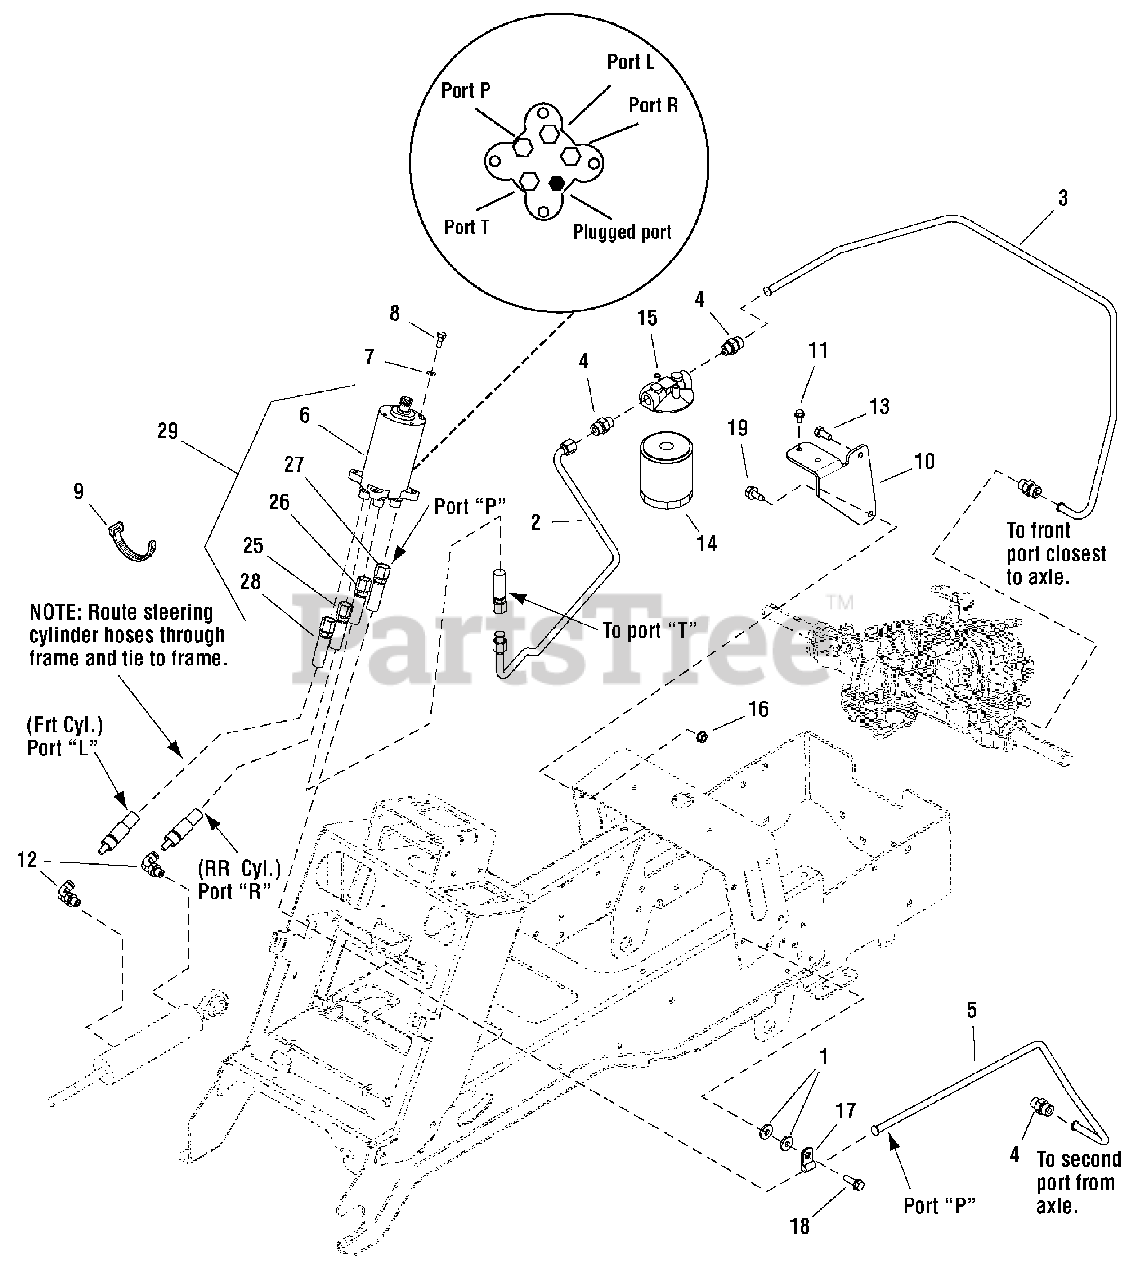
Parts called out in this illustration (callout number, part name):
1	WASHER, Flat, 5/16
2	TUBE, Filter
3	TUBE, Hydro
4	FITTING, Hydraulic, Straight
5	TUBE, Hydro
6	POWER STEERING UNIT
7	LOCKWASHER, Spring, 1/4
8	CAPSCREW, Hex, M06, 1.0 x 16mm
9	TIE, Wire
10	SUPPORT, Filter
11	SCREW, Whiz-Lock, 1/4-20 x .50
12	FITTING, Perma-Push
13	CAPSCREW, Hex, 5/16-18 x .75
14	FILTER, Oil
15	MANIFOLD, Oil Filter
16	NUT, KEPS-Lock, 5/16-18
17	CLIP
18	SCREW, Taptite, 5/16-18 x 1.0
19	SCREW, Taptite, 5/16-18 x .75
25	HOSE ASSEMBLY, Hydraulic Rubber, 27"
26	HOSE ASSEMBLY, Hydraulic Rubber, 18"
27	HOSE ASSEMBLY, Hydraulic Rubber, 26"
28	HOSE ASSEMBLY, Hydraulic Rubber, 31"
29	POWER STEERING ASSEMBLY, 32 CC, 4 Ports
